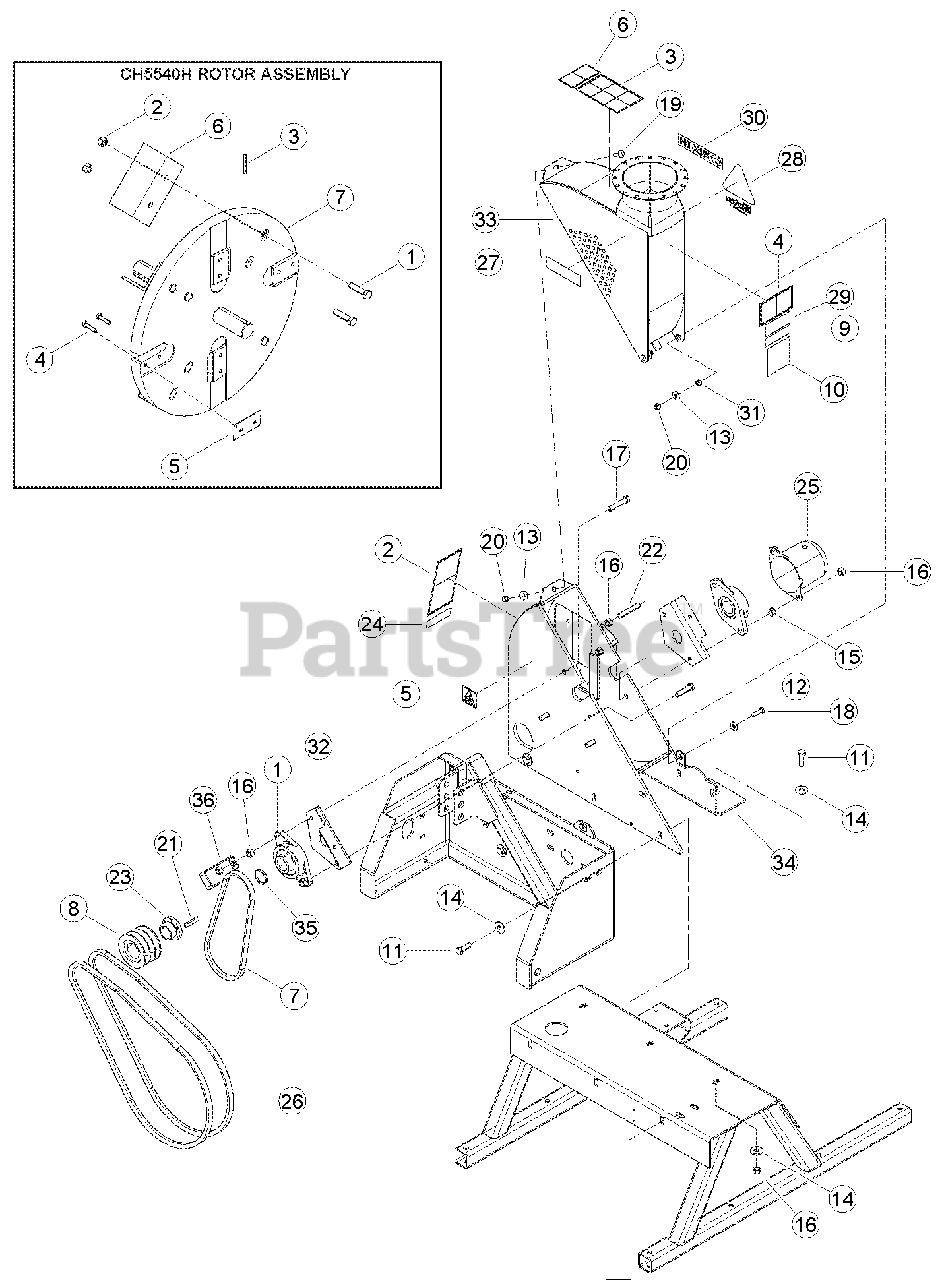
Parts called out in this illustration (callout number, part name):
1	BOLT, 1/2 X 2 HEX HD GR5 ZP
2	NUT, 1/2 CENTERLOCK GRB ZP
3	SPRINGPIN, 1/4 X 2 LONG
4	BOLT, 5/16 X 1-1/4 HHD GR8 PATCH
5	KIT, CHIPPER BLADE
7	WELDMENT, CHIPPER DISK
